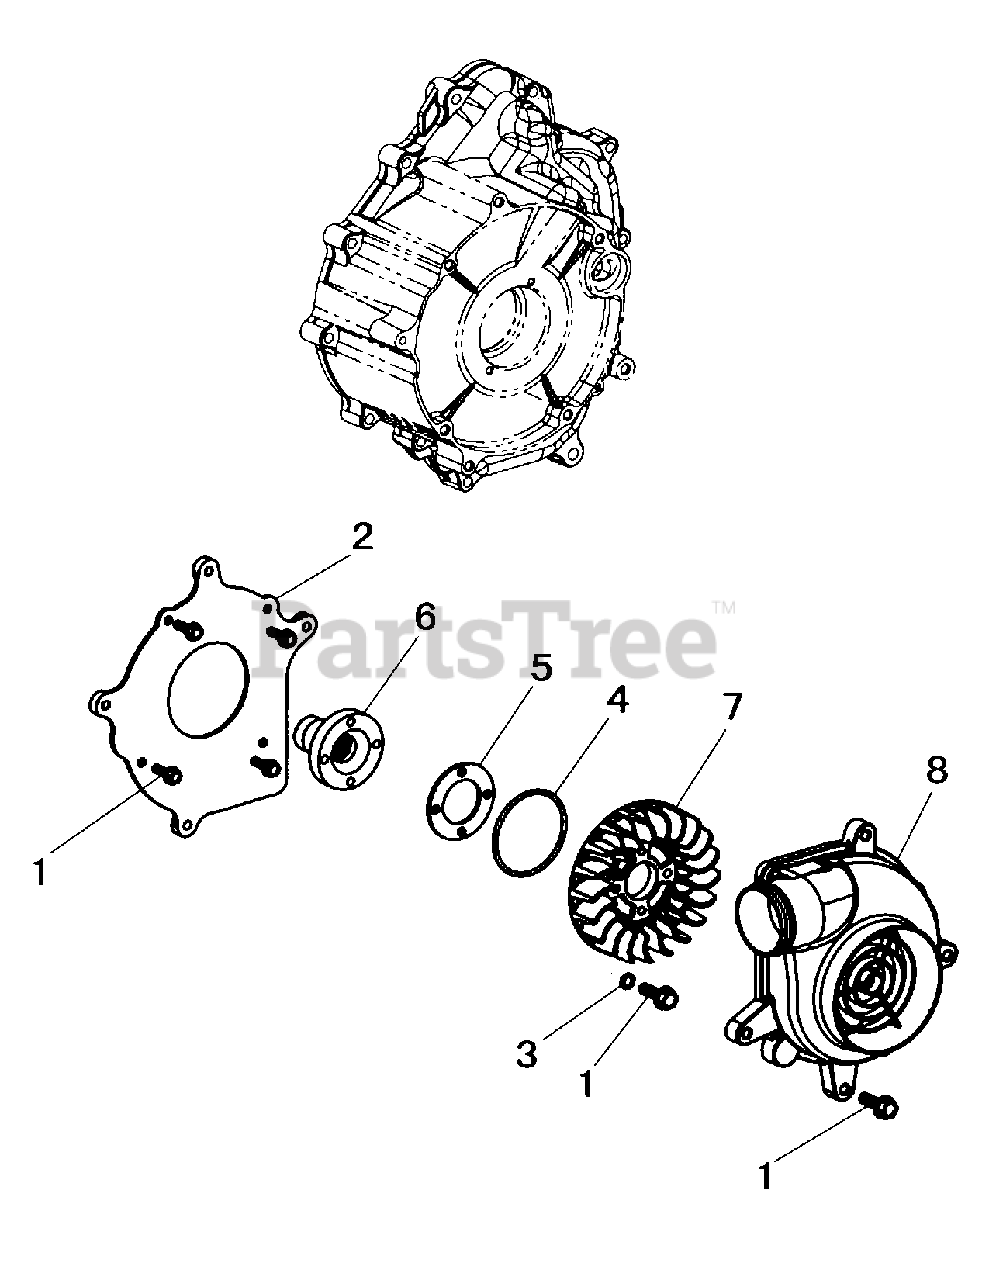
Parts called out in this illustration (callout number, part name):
1	Flange Bolt M6X20
2	Mounting Board
4	O-Ring 64.4X3.1
5	Plate-Fan Station
6	Starter Pulley
8	Cover-Outer Clutch
